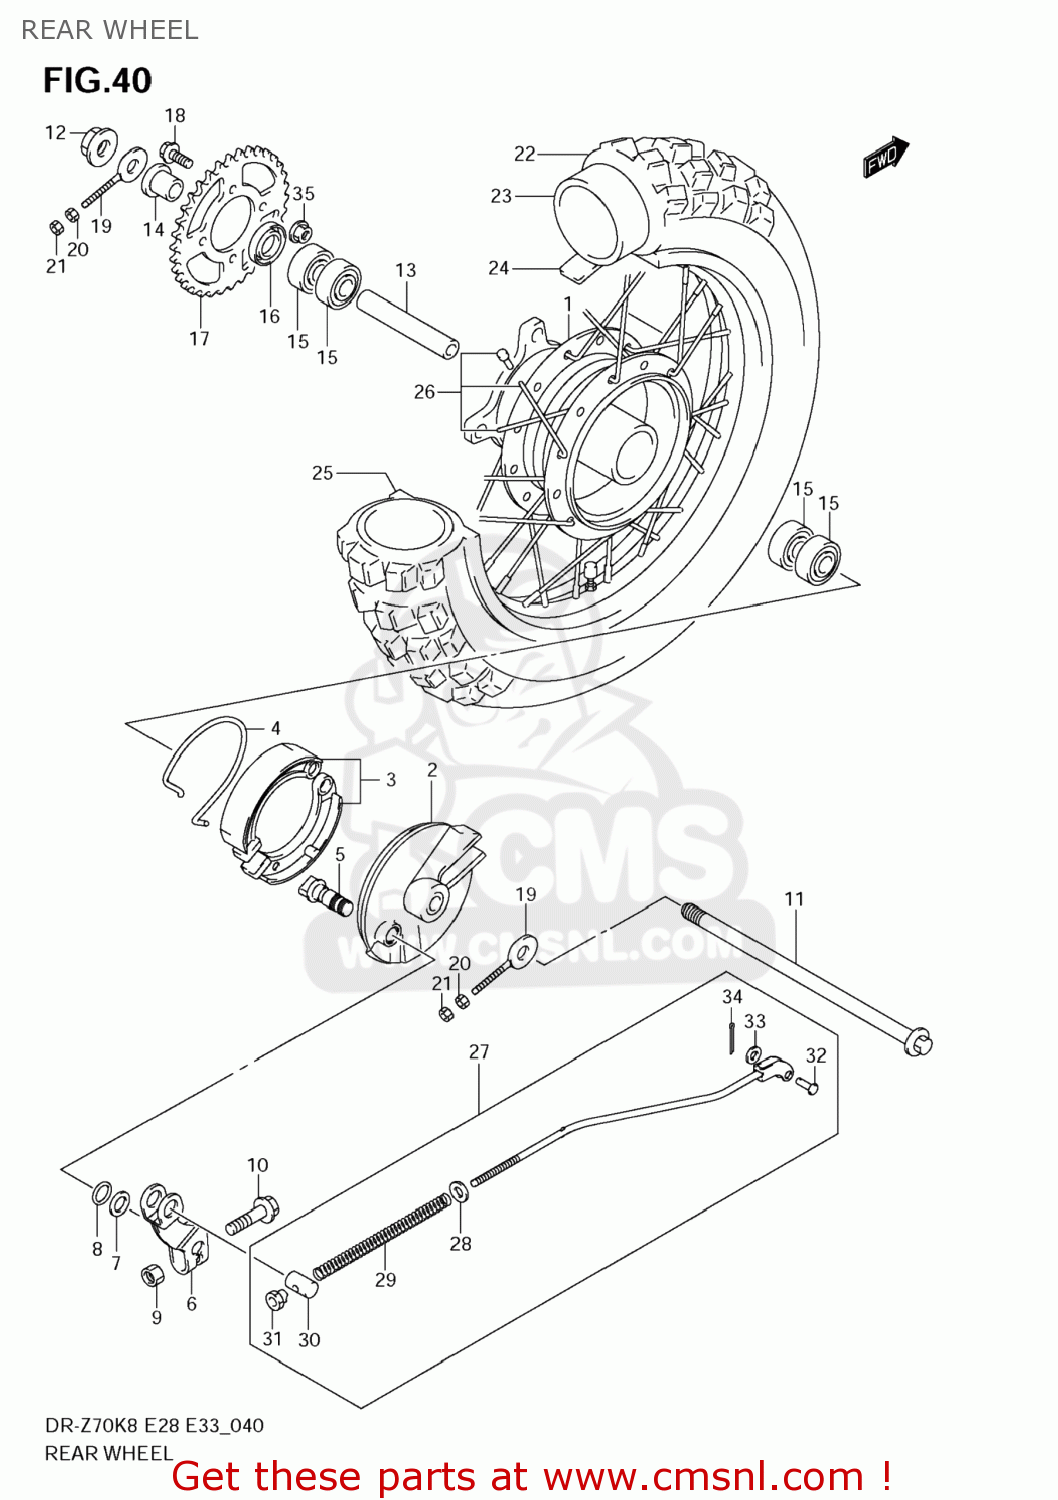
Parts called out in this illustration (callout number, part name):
1	HUB,RR WHEEL
2	PANEL,FR BRAKE ANCHOR
3	SHOE SET,BRAKE (NAS)
4	SPRING,BRAKE SHOE
5	CAM,BRAKE
6	LEVER,BRAKE CAM
7	WASHER(10.5X18X1)
8	O RING(D:2.4,ID:9.8)
9	NUT
10	BOLT
11	AXLE,RR
12	NUT
13	SPACER(12.5X19X105.5)
14	SPACER,RR AXLE,L
15	BEARING (12X32X10)
16	SEAL,OIL(32X20X5)
17	SPROCKET,RR(33T-428)
18	BOLT(8X28)
19	ADJUSTER,CHAIN
20	NUT
21	NUT
22	TIRE(2.50 10)
23	TUBE ASSY,WHEEL INNER
24	PROTECTOR,WHL INR TUBE
25	RIM,WHEEL(10X1.40)
26	SPOKE SET,WHEEL
27	ROD ASSY,RR BRAKE
28	WASHER
29	SPRING
30	PIN(11X18)
31	NUT
32	PIN(L:13.5)
33	WASHER
34	PIN
35	NUT
